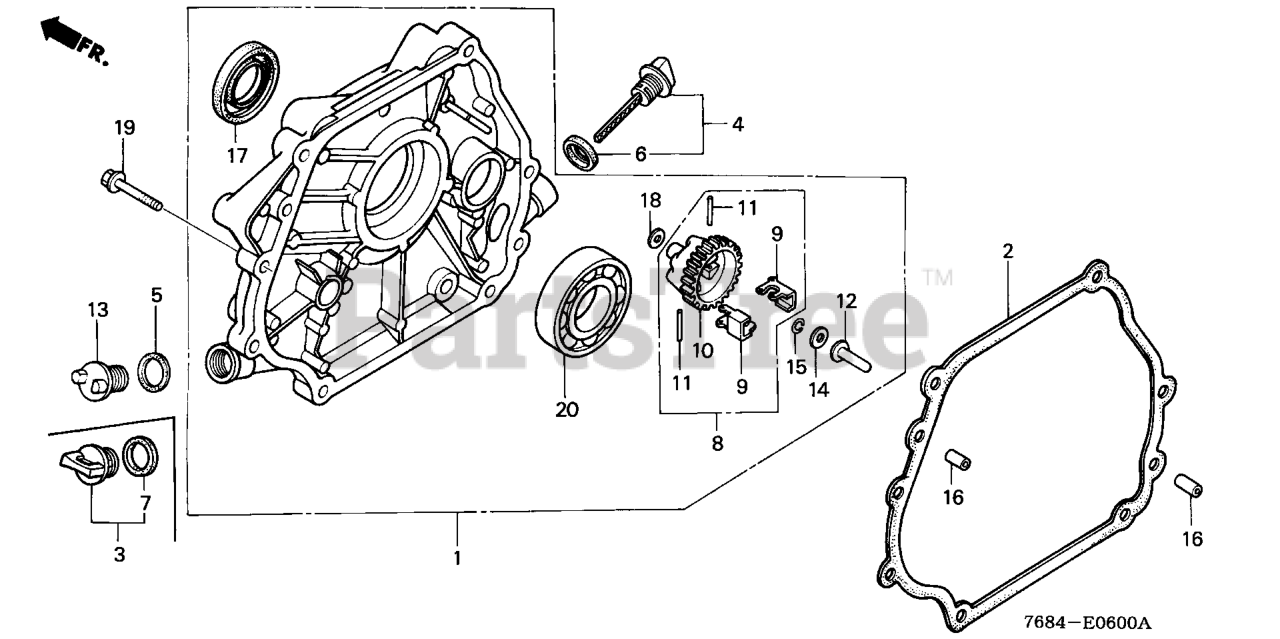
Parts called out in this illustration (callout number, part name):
1	COVER ASSY., CRANKCASE (Honda Code 2159853). (S-TYPE)
1	COVER ASSY., CRANKCASE
2	GASKET, CASE COVER
3	CAP ASSY., OIL FILLER
4	CAP ASSY., OIL FILLER
6	GASKET, OIL FILLER CAP
7	GASKET, OIL FILLER CAP
8	GOVERNOR ASSY. (STD)
9	WEIGHT, GOVERNOR
10	HOLDER, GOVERNOR WEIGHT
11	PIN, GOVERNOR WEIGHT
12	SLIDER, GOVERNOR
15	CLIP, GOVERNOR HOLDER
16	PIN, DOWEL (8X12)
17	OIL SEAL (30X46X8)
18	WASHER, PLAIN (6MM)
19	BOLT, FLANGE (8X35)
20	BEARING, RADIAL BALL (6206)
